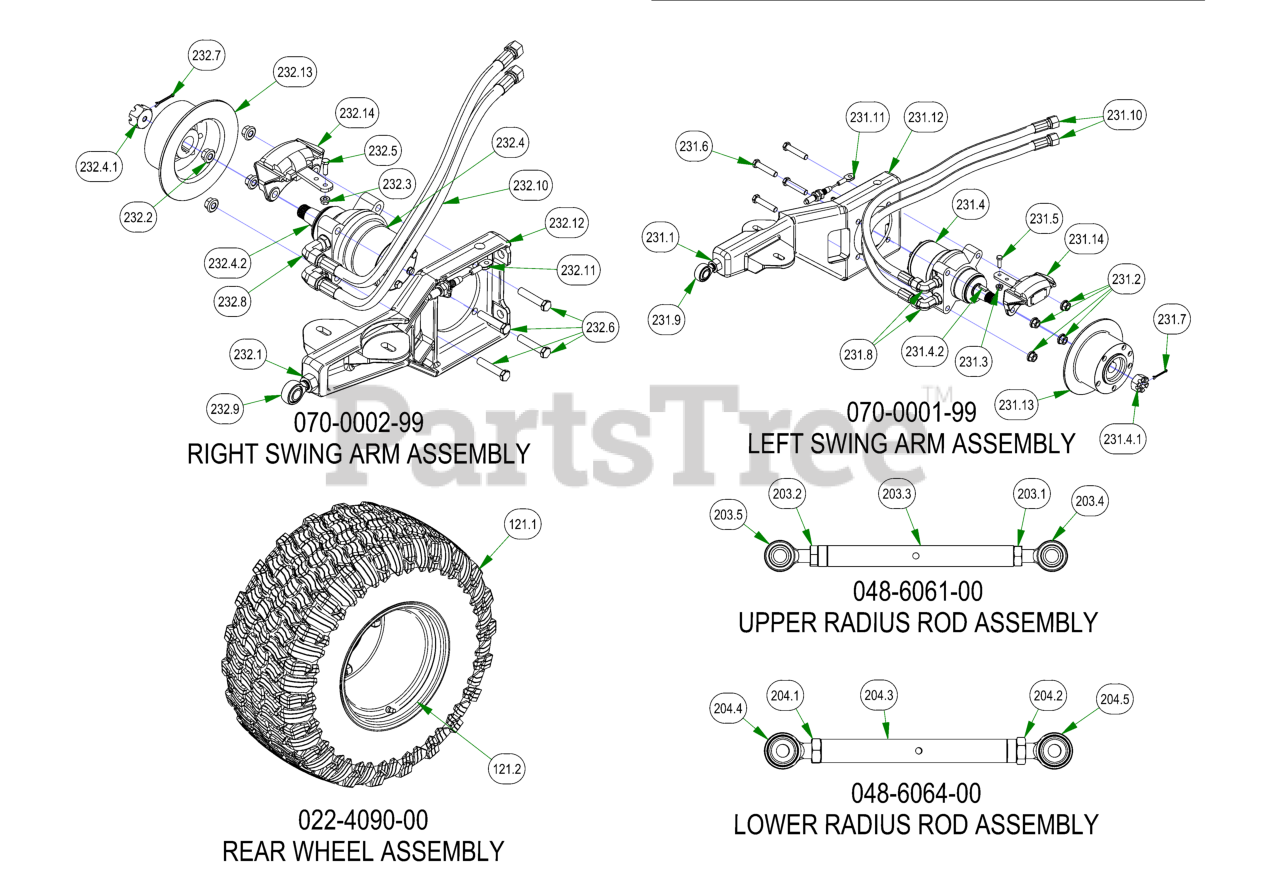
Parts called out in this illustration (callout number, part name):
121	2019 Assy-26x12-12 Reaper Turf -10.5" Rim
121.1	2019 26x12-12 Reaper Turf Tire
121.2	2019 10.5" Wheel
203	2019 Suspension Radius Rod Assembly
203.1	5/8-11 HEX JAM NUT ZINC
203.2	NUT, 5/8-18LH
203.3	2019 Suspension Link Body
203.4	2019 RH 5/8" Heim
203.5	2019 LH 5/8" Heim
204	2019 Suspension Radius Rod Assembly
204.1	3/4-16 HEX JAM NUT ZINC
204.2	3/4-16 LH HEX JAM NUT ZINC
204.3	Rear Radius Rod, 3/4 Body
204.4	3/4-16 x 5/8 RH Heim
204.5	3/4-16 x 5/8 LH Heim
231	2019 Renegade Trailing LH Arm Assy
231.1	3/4"-16 Fine Full Nut
231.2	1/2-13 Gr 8 Centerlock Flange Nut
231.3	5/16-18 NYLON INSERT FLANGE LOCKNUT ZINC
231.4	18cc Parker Wheel Motor- Left
231.4.1	1" Castle Nut for HydroGear Wheel Motor
231.4.2	Woodruff Key
231.5	5/16-18 X 1 HEX CAP SCREW (GR.5) ZINC
231.6	1/2-13 x 2.75 Gr. 8 Hex Head Bolt
231.7	1/8 X 1-1/2 COTTER PIN ZINC
231.8	2019 Rouge/Renegade Wheel Motor 90* Fitting #6801-10L
231.9	3/4-16 RH Male Rod End
231.10	2019 Renegade Hydro Hose
231.11	2019 Short Brake Cable-Suspension Models
231.12	2019 Left Trailing Arm
231.13	Brake Disk
231.14	XP/AOS Left Brake Caliper
232	2019 Renegade Trailing RH Arm Assy
232.1	3/4"-16 Fine Full Nut
232.2	1/2-13 Gr 8 Centerlock Flange Nut
232.3	5/16-18 NYLON INSERT FLANGE LOCKNUT ZINC
232.4	18cc Parker Wheel Motor- Right
232.4.1	1" Castle Nut for HydroGear Wheel Motor
232.4.2	Woodruff Key
232.5	5/16-18 X 1 HEX CAP SCREW (GR.5) ZINC
232.6	1/2-13 x 2.75 Gr. 8 Hex Head Bolt
232.7	1/8 X 1-1/2 COTTER PIN ZINC
232.8	2019 Rouge/Renegade Wheel Motor 90* Fitting #6801-10L
232.9	3/4-16 RH Male Rod End
232.10	2019 Renegade Hydro Hose
232.11	2019 Long Brake Cable-Renegade, Rogue
232.12	2019 Right Trailing Arm
232.13	Brake Disk
232.14	XP/AOS Right Brake Caliper
